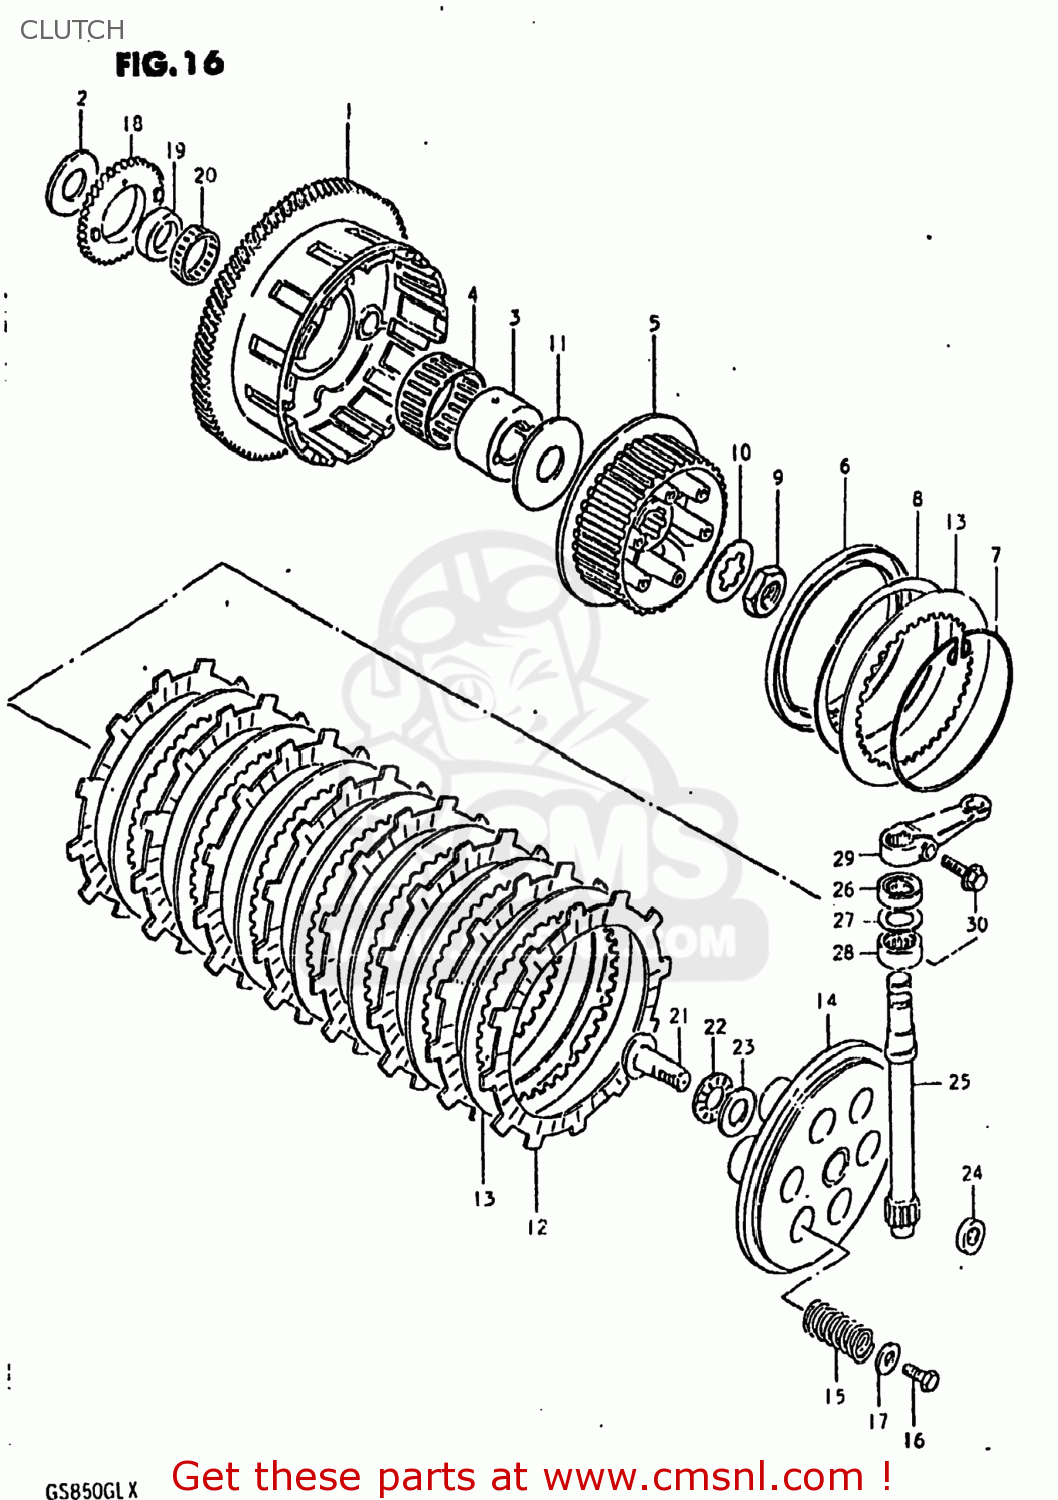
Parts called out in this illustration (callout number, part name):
1	GEAR ASSEMBLY,PRIMARY DRIVE
2	WASHER
3	SPACER,PRIMARY DRIVEN
4	BEARING
5	HUB,CLUTCH SLEEVE
6	SEAT,WAVE WASHER
7	RING,STOPPER
8	WASHER
9	NUT
10	WASHER,LOCK
11	WASHER(25X66X3.5)
12	PLATE,CLUTCH DRIVE (MCA)
13	PLATE,CLUTCH DRIVEN(T:2.0) (NAS)
14	DISC,CLUTCH PRESSURE
15	SPRING
16	BOLT, UPPER
17	WASHER
18	GEAR,OIL PUMP DRIVE
19	SPACER,OIL PUMP DRIVE GEAR
20	BEARING(36X40X10)
21	RACK,CLUTCH RELEASE
22	BEARING(15X28X2)
23	WASHER
24	SEAL,OIL(10X16X5)
25	PINION,CLUTCH RELEASE
26	OIL SEAL
27	WASHER (14.2X22X1)
28	BEARING(15X22X12)
29	ARM,CLUTCH RELEASE
30	BOLT,REAR
